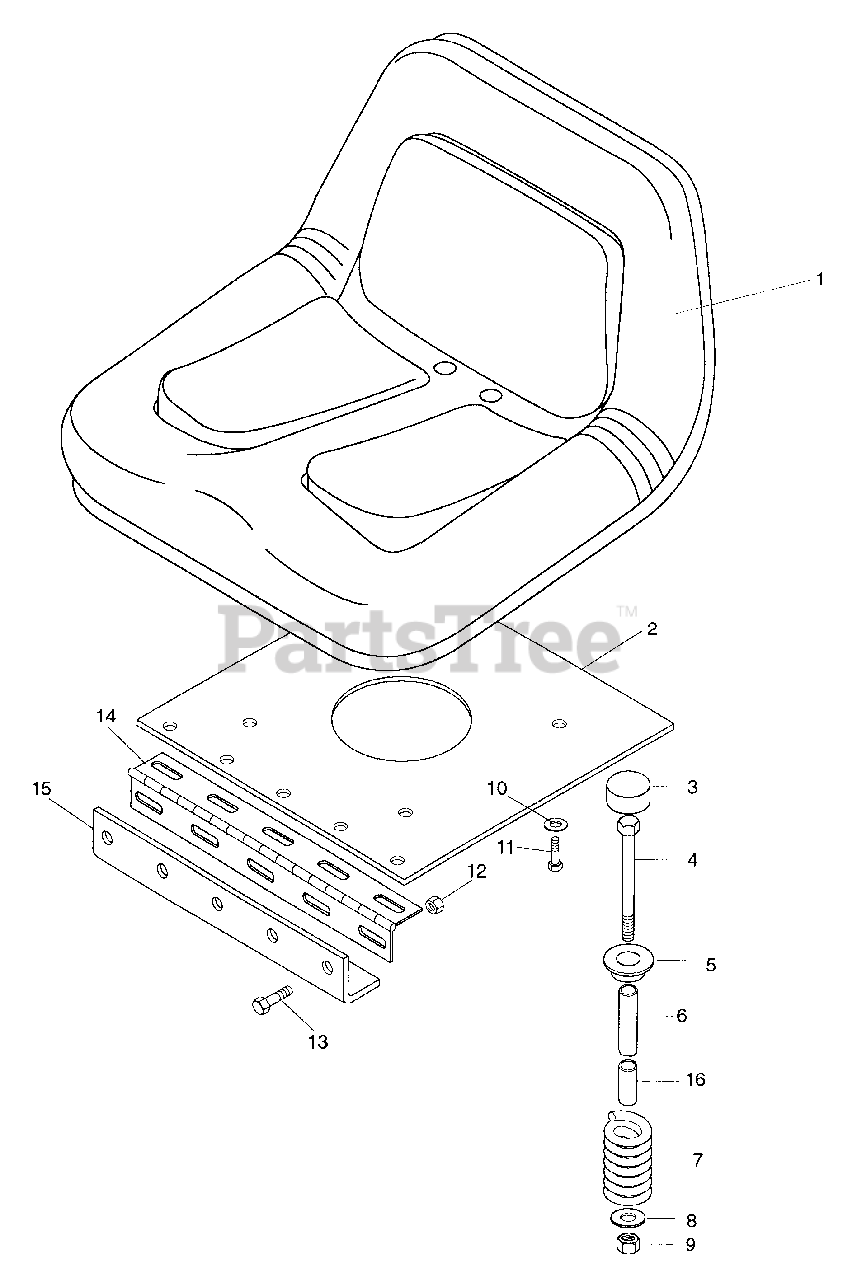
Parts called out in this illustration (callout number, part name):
1	Seat High Back
2	Plate, Seat Mounting
3	Tip, Rubber
4	Bolt - Hex .25 - 20 x 2.25
5	Cap, Valve Spring
6	Bushing, Split Rolled
7	Spring, Compression .148 x 1.095 x 1.75
8	Washer-Flat-Steel .344 x .688 x .065
9	Nut-Locking-Nylon .250-20 Grade 2
10	Washer-Lock .313 x .078
11	Bolt-Hex Metric 8M-1 .25 x 35MM Grade 8
12	Nut-Locking-Nylon .312-18 Grade 2
13	Bolt-Hex .31-18 x .625
14	Hinge
15	Bracket, Seat Support
15	Kit, Arm Rest G Series
16	Bushing, Split Rolled
